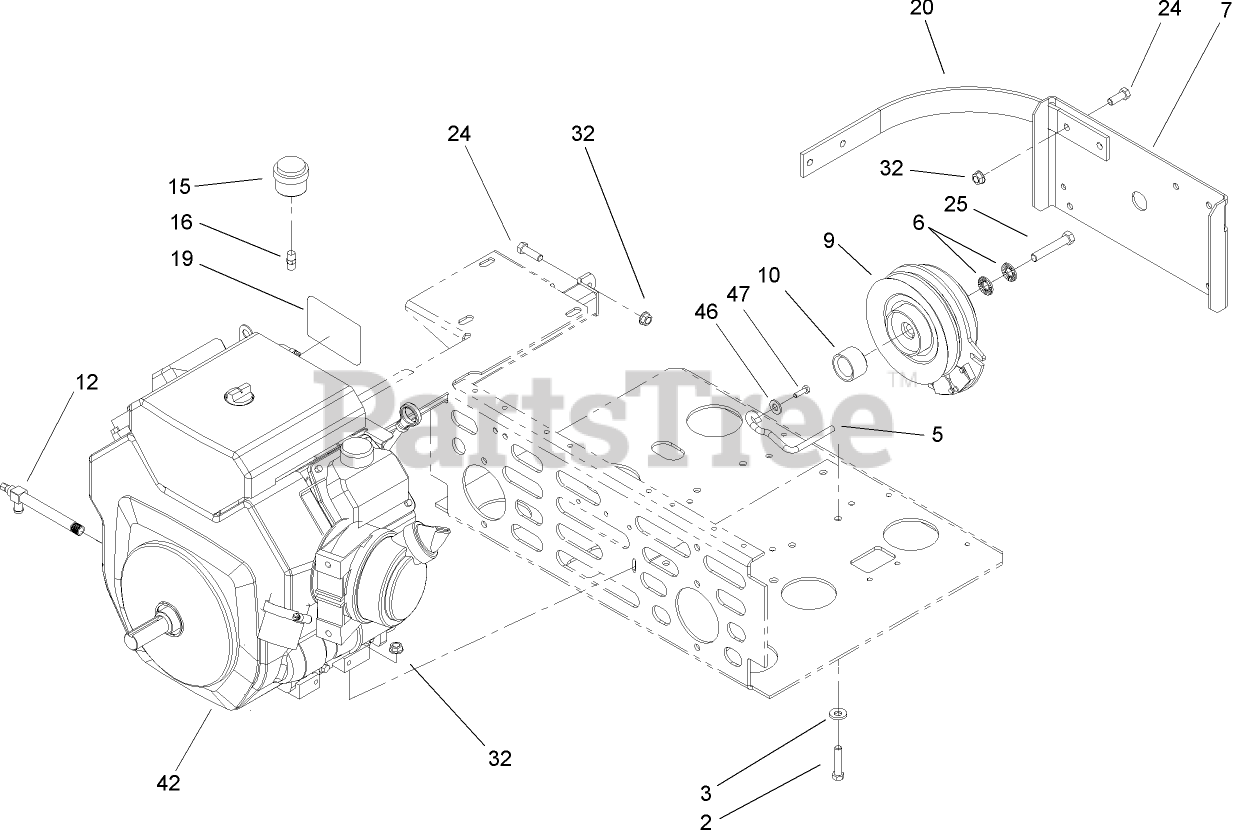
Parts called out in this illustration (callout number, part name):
2	SCREW-HH
3	WASHER-BELLEVILLE
5	ROD-BELT
6	WASHER-SPRING
7	GUARD-CLUTCH
9	Clutch
10	SPACER-CLUTCH
12	VALVE-OIL DRAIN, LONG
15	INDICATOR-FILTER, AIR
16	ADAPTER-INDICATOR
20	BRACKET-GUARD, TOP
24	SCREW-HH
25	SCREW-HH
32	NUT-HHF, WHIZ
46	WASHER-FLAT
47	SCREW-HH
